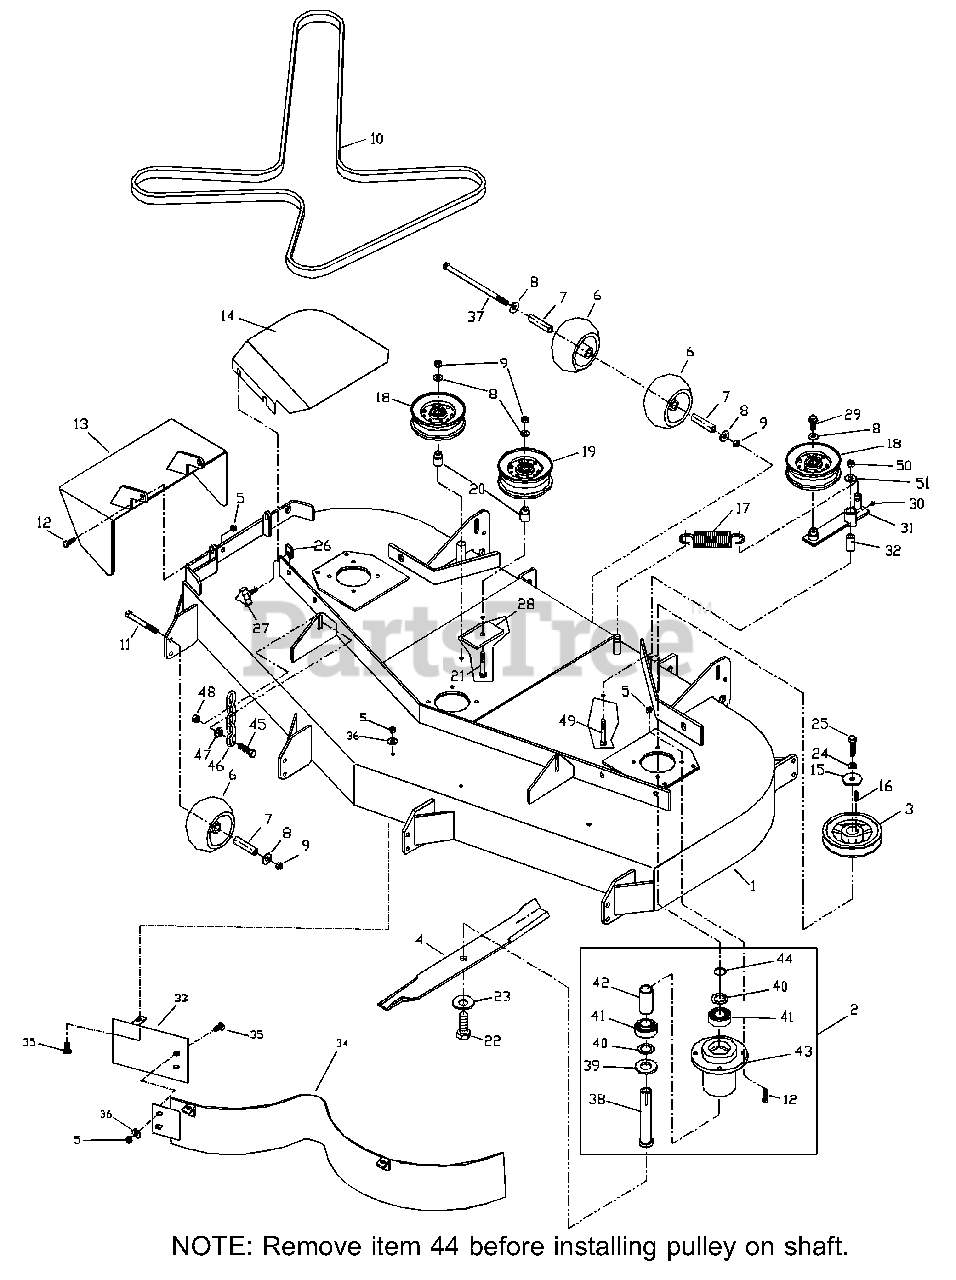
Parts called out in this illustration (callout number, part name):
1	DECK W/DECALS
2	CUTTER HOUSING ASM
5	NUT 5/16 LOCK
8	3/8 FLAT WASHER
9	NUT 3/8 LOCK
11	HCS 3/8 X 3.5
12	HCS 5/16 X 1.25
13	DISCHARGE CHUTE
14	BELT SHIELD RT.
14	BELT SHIELD LT.
16	KEY 1/4 SQ.
18	PULLEY 1.31
19	PULLEY 1.62
20	IDLER BUSHING
21	HCS 3/8 X 3.0
22	HCS 5/8F X 2.0 GD. 8
23	5/8 SPRING WASHER
24	7/16 LOCK WASHER
25	HCS 7/16F X 1.5
27	KNOB
28	PAD
29	HCS 3/8 X 1.0 SERR.
30	ZERK
32	PIVOT BUSHING
33	BAFFLE, CENTER
34	BAFFLE, MAIN
35	RHSNB 5/16 X 5/8
36	5/16 FLAT WASHER
37	HCS 3/8 X 6.0 GD. 8
39	MACHINE BUSHING
40	MACHINE BUSHING
41	BEARING
45	HCS 7/16 X 1.5
47	NUT 7/16 WHIZ
48	NUT 7/16 LOCK
49	HCS 1/2 X 3.25
50	NUT 1/2 NYLOC
51	WASHER 1/2 FLAT
